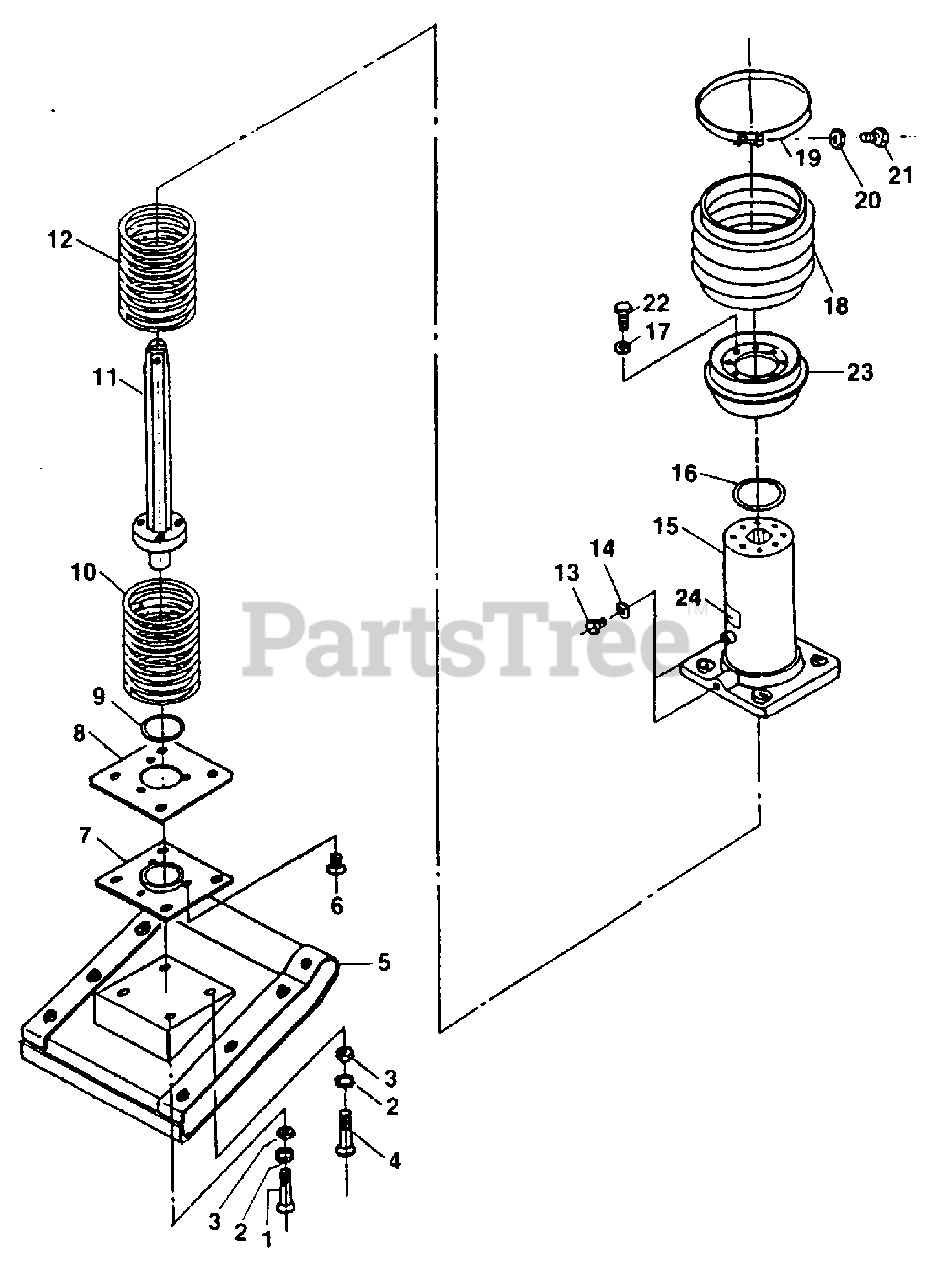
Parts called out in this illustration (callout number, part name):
1	BOLT- Foot m12
2	WASHER- Spring m12
3	NUT- Nylon m12
4	BOLT- Foot
6	BOLT- Flat
7	COVER- Cylinder
9	O-RING (G-120)
10	SPRING- Coil (Lower)
11	SHAFT- Ram
12	SPRING- Coil (Upper)
13	BOLT- Hex m8 x 16
14	GASKET- Copper m8
15	CYLINDER- Foot
16	O-RING (G-100)
17	WASHER- Spring m8
19	BELLOWS BAND
20	NUT- Hex m10
21	BOLT- Hex m10 x 60
22	BOLT- Hex m8 x 25
23	BELLOWS BASE
24	CHECK OIL DECAL
